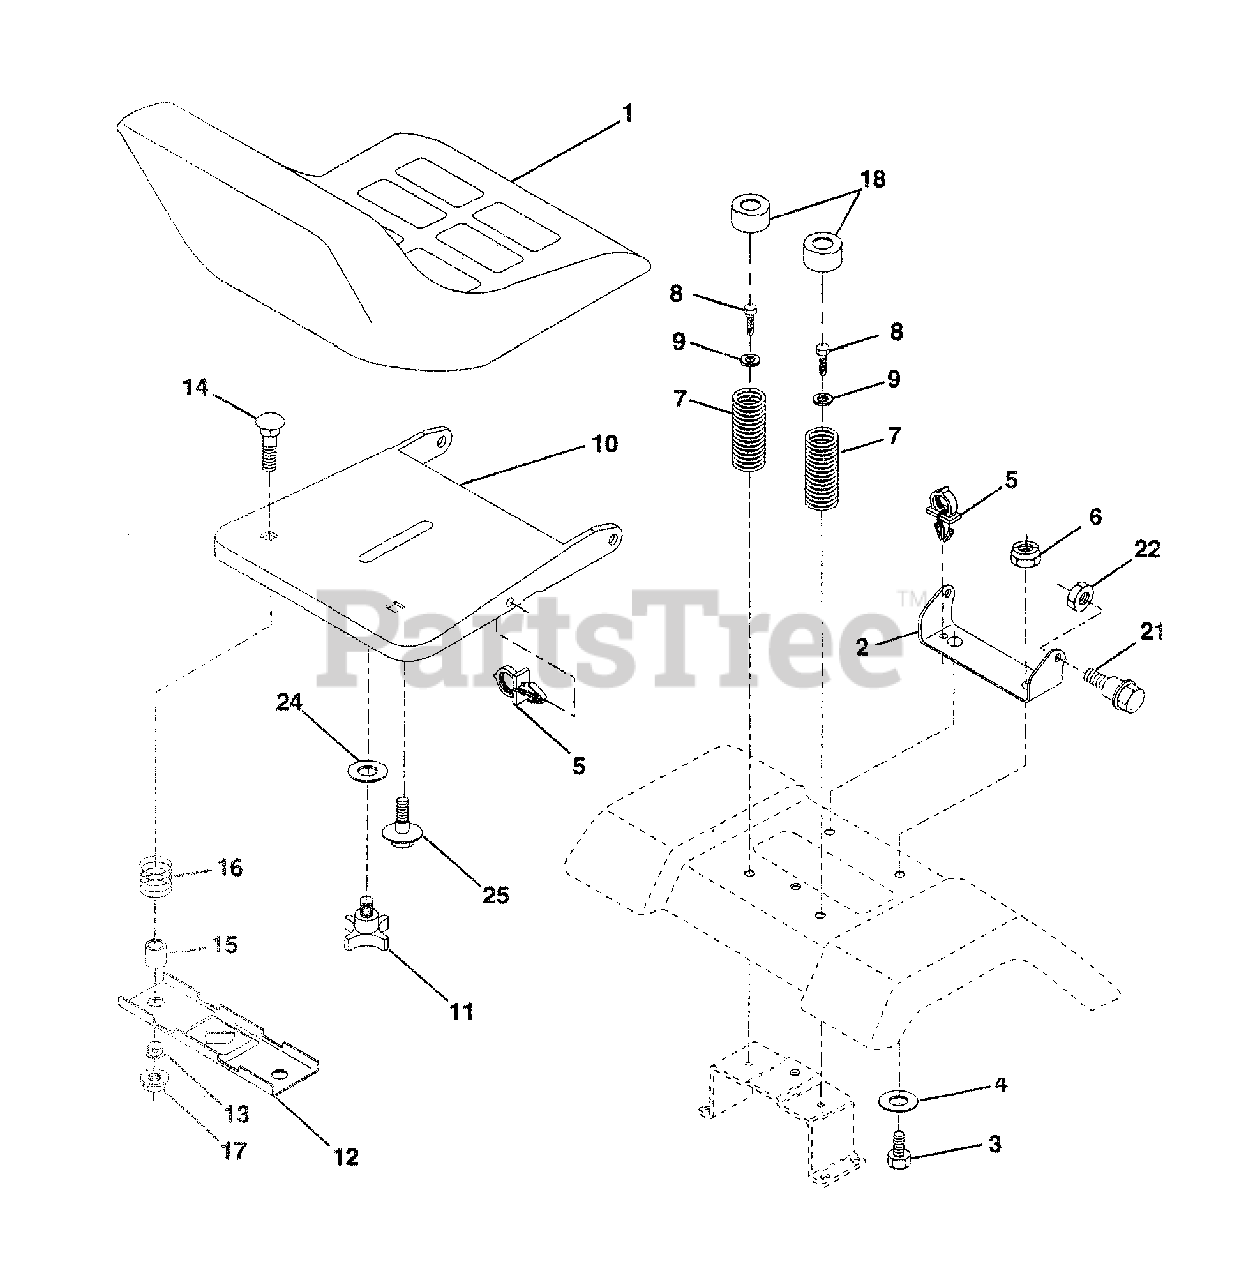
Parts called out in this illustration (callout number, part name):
1	Seat V450 Grey/blk Std
2	Bracket Pivot Seat 8 720
3	Bolt Fin Hex 3/8-16unc X 1
4	Washer 13/32 X 1 X 10 Ga
5	Clip Push-In
6	Nut Lock 3/8-16 Unc
7	Spring Seat Cprsn 2 250 Blk ZI
8	Screw Thdrol 3/8-16 X 1 Ty-ft
9	Washer 13/32 X 1 X 14 Ga.
10	Pan Seat
11	Knob Seat 1/2-13 UNC Blk
12	Bracket Mounting Switch
13	Bushing Snap Blk Nyl 50 ld
14	Bolt Rdhd Sht Nk 1/4-20x1-3/8
15	Spacer Split 28x 96 yel Zinc
16	Spring Cprsn 1 27 Blk Pnt
17	Nut Lock 1/4 Lge Flg Car 5 Zinc
18	Cap Spring Seat
21	Bolt Shoulder 5/16-18 Unc-2A
22	Nut Hex Lock W/Ins 5/16-18
24	Washer 17/32 X 1-3/16 X 12 Ga.
25	Bolt Shoulder 5/16-18 X 62
